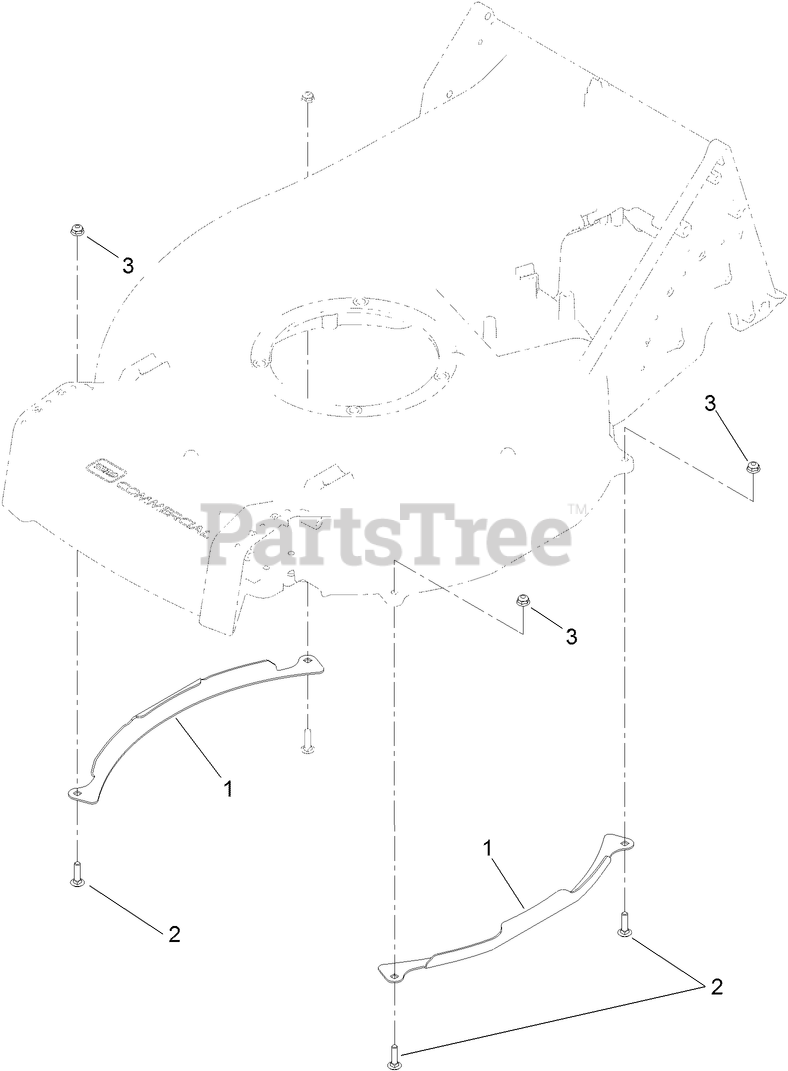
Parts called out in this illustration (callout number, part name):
1	GUARD-SIDE, DECK
2	SCREW-CARR
3	NUT-HF
